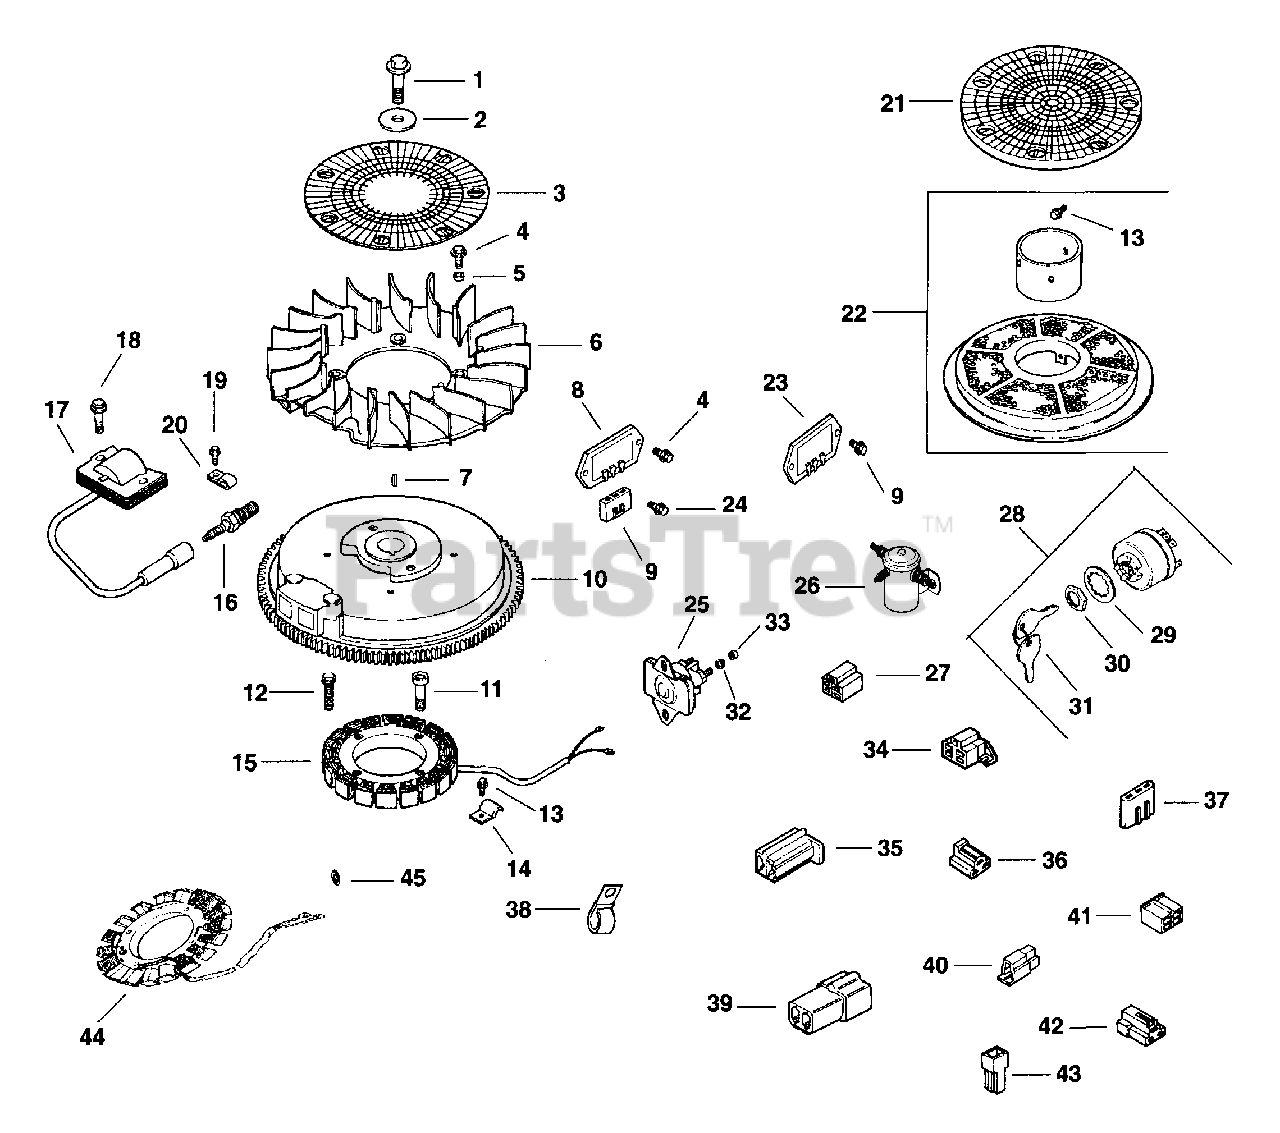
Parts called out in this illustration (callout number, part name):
1	SCREW, FLG M10X1.5X45 - (#25086361S)
2	WASHER, FLAT 13/32"
4	SCREW - USE M-639016
5	BOLT - USE 25 086 47
6	FAN - USE 12 157 03
7	KEY, 3/16" X 5/8"
10	FLYWHEEL - USE 12 025 29
12	SCREW, WSH HD TAP #10-32x9/16" USE 25 086 110-S
13	SCREW - USE M-545010
16	PLUG, SPARK (STD)
17	MODULE - USE 12 584 05
18	Screw, hex. flange M5x0.8x20
